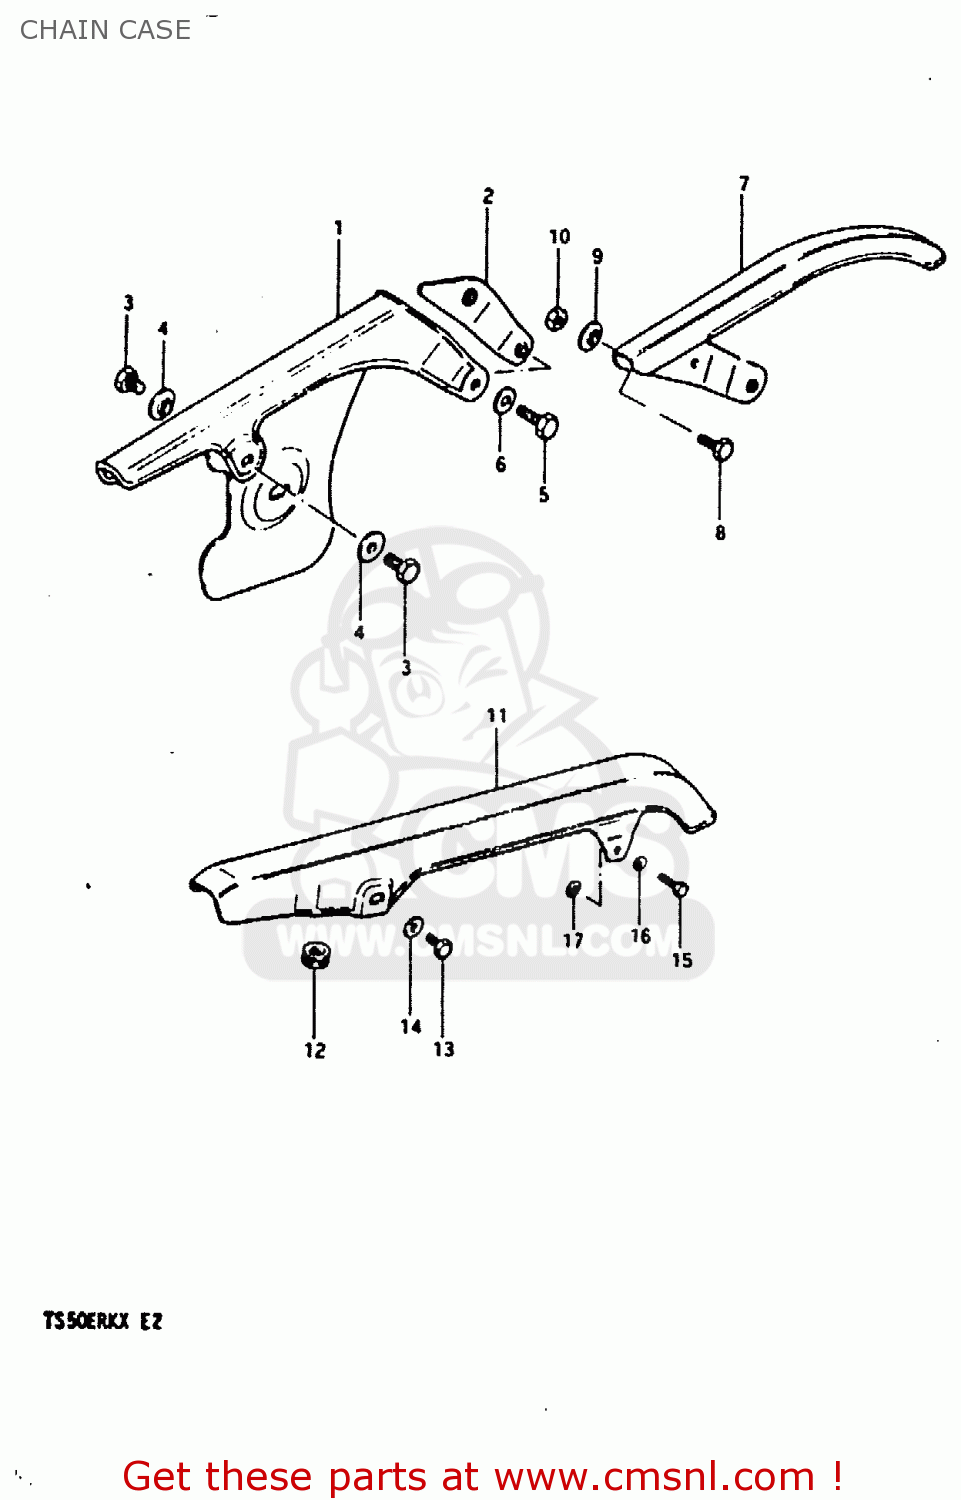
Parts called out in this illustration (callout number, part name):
1	CASE,CHAIN
2	REINFORCEMENT,CHAIN CASE
3	BOLT(6X8)
4	WASHER
5	BOLT, UPPER
6	WASHER
